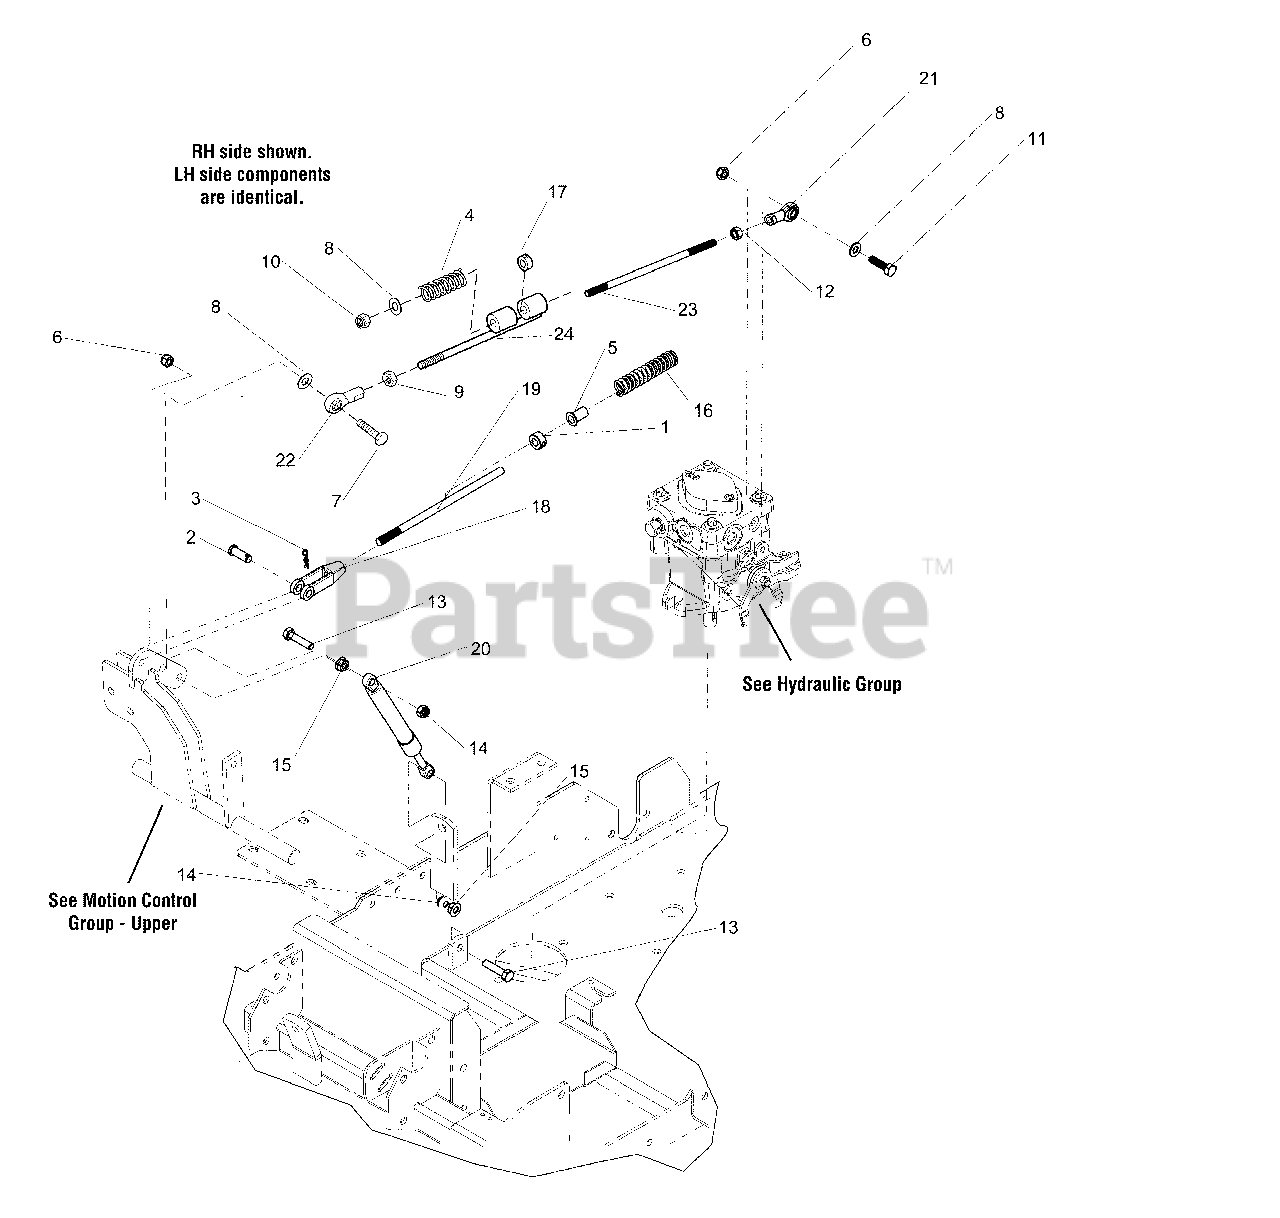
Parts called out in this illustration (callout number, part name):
1	COLLAR, 3/8" SET
2	PIN, CLEVIS, 3/8" X 1"
3	PIN, HAIR, .0585 X 1-1/8
4	SPRING, CONTROL ROD
5	BUSHING, FLANGE 3/8ID X 7/8 LONG
6	NUT 5/16-18 HEX NYLON LOCK
7	BOLT, 5/16-18 X 1-1/4" GD5
8	WASHER, 5/16" SAE
9	NUT, HEX 5/16-24
10	NUT 5/16-24 HEX NYLON LOCK
11	BOLT, 5/16-18 X 1-1/8" GD5
12	NUT, 5/16 HEX LH
13	BOLT, M8-1.25 x 35MM
14	NUT, M8-1.25 Hex Nylon Lock
15	NUT, M8-1.25 Hex Serrated Flange
16	SPRING, COMPRESSION
17	SET COLLAR, 5/16"
18	CLEVIS, 3/8-24, PLASTIC
19	ROD, NEUTRAL CONTROL, 8"
20	DAMPENER
21	BALL JOINT 5/16-24 LH FEMALE STAMPED STL
22	BALL JOINT 5/16-24 RH FEMALE STAMPED STL
23	ROD, 5/16 X 8.38, LH-RH, CZ
24	ROD ASSEMBLY, SLIDER
